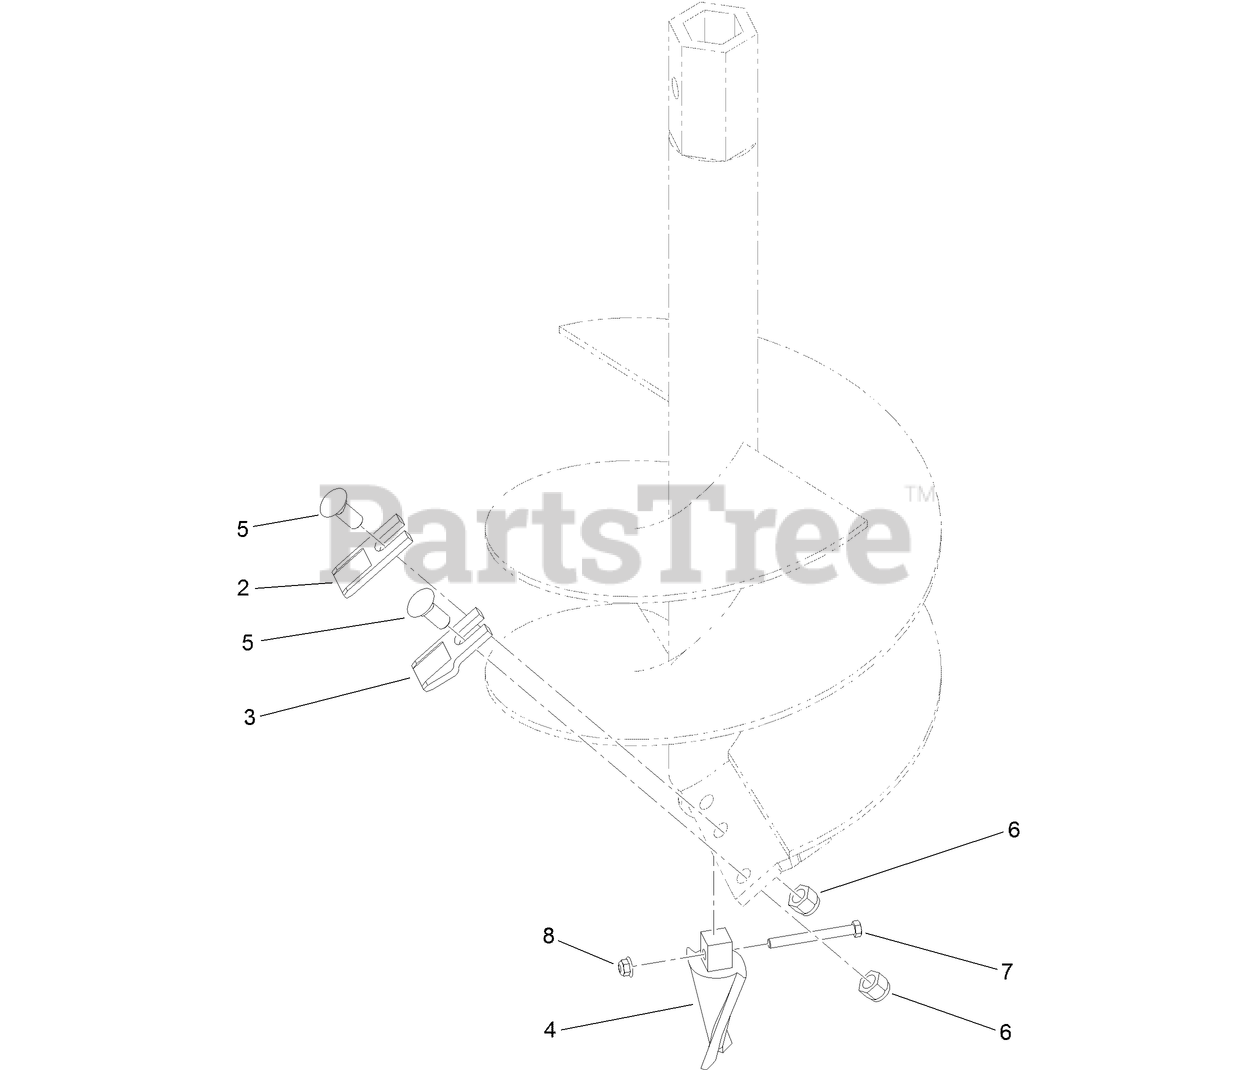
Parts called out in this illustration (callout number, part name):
2	TOOTH-AUGER, WISDOM (INSIDE)
3	TOOTH-AUGER, WISDOM (OUTER)
4	TOOTH-FISHTAIL, STANDARD
5	SCREW-CARRIAGE
6	NUT-LOCK, NI
7	SCREW-HH
8	NUT-HF, NI
